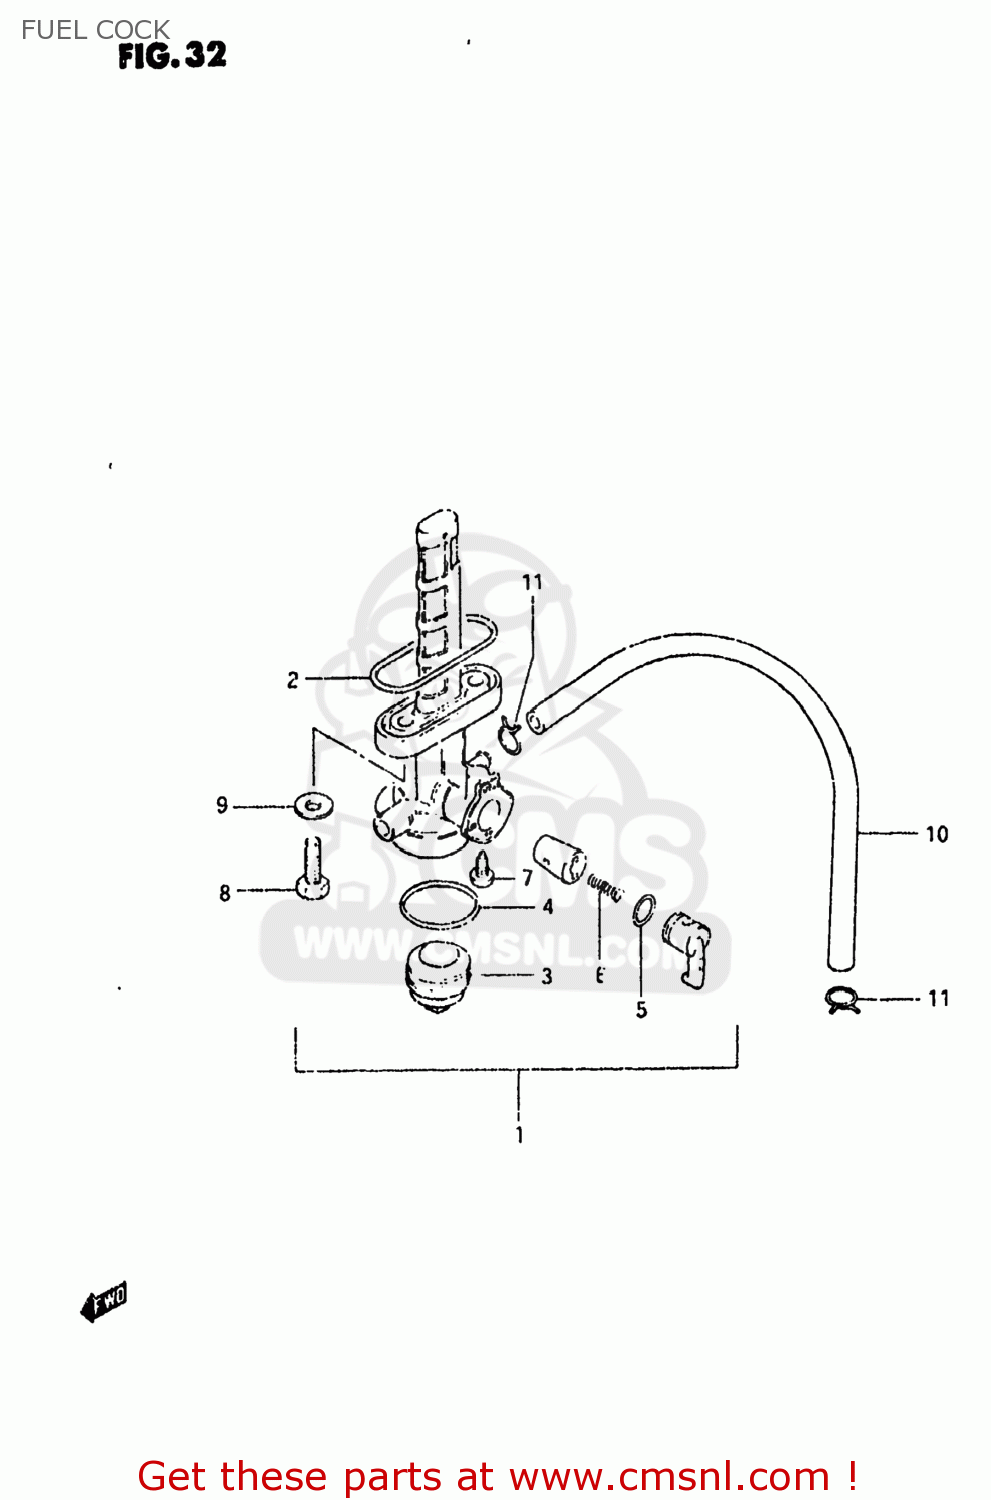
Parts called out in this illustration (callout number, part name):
1	COCK ASSEMBLY,FUEL
2	O RING,FUEL COCK
3	CUP,STRAINER
4	GASKET,FILTER (NAS)
5	O-RING
6	SPRING
7	SCREW
8	BOLT(6X20)
9	GASKET
10	HOSE
11	CLIP
